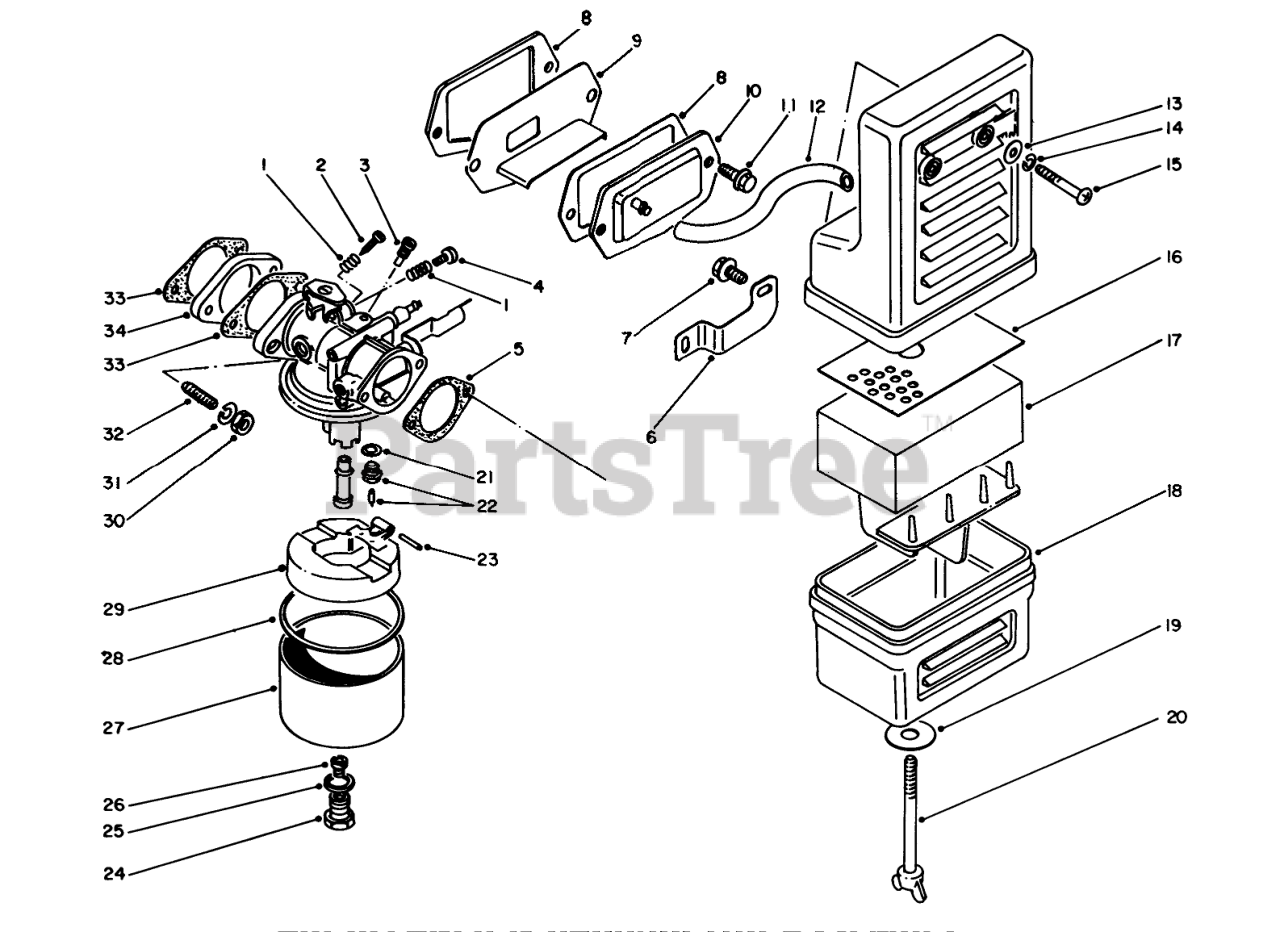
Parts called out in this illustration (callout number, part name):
1	Spring
2	ADJUSTER
3	Jet
4	Screw
5	AIR CLEANER GASKET
6	Bracket
8	GASKET
9	Reed Valve Assembly
13	WASHER
14	Washer
15	SCREW
16	Holder
17	FILTER
18	Air Cleaner Assembly (Incl. Ref. #16, 17, 19, 20)
19	WASHER
20	Bolt-Wing
21	GASKET
22	NEEDLE VALVE
25	Gasket
27	Carburetor Assembly (Incl. Ref. #21-26, 28, & 29)
28	GASKET
29	Float
31	Lockwasher
32	Bolt-Stud
33	Gasket
34	INSULATOR
